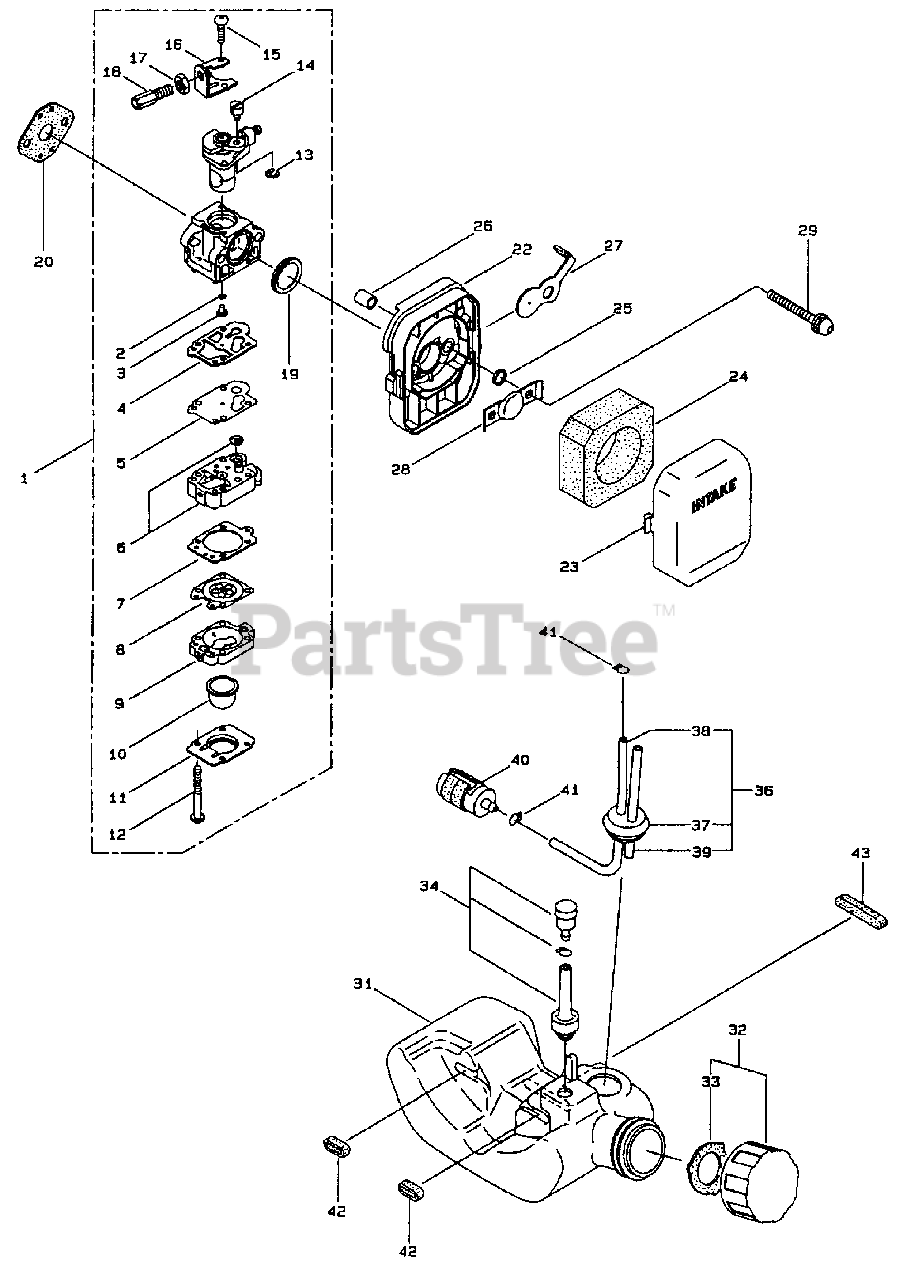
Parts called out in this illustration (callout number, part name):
1	Carburetor Assembly (Incl. Ref. # 2-19)
3	Main Jet
5	Diaphragm
6	Pump Body
8	Diaphragm
9	Purge Body
10	Primer Bulb
11	Cover Plate
15	Screw
27	Choke Valve
29	Cap Screw
31	Fuel Tank
32	Fuel Tank Cap Assembly (Incl. Ref. # 34)
34	Breather Assembly
36	Fuel Pipe Assembly (Incl. Ref. # 38-40)
38	Fuel Pipe
39	Return Pipe
40	Fuel Filter Assembly
